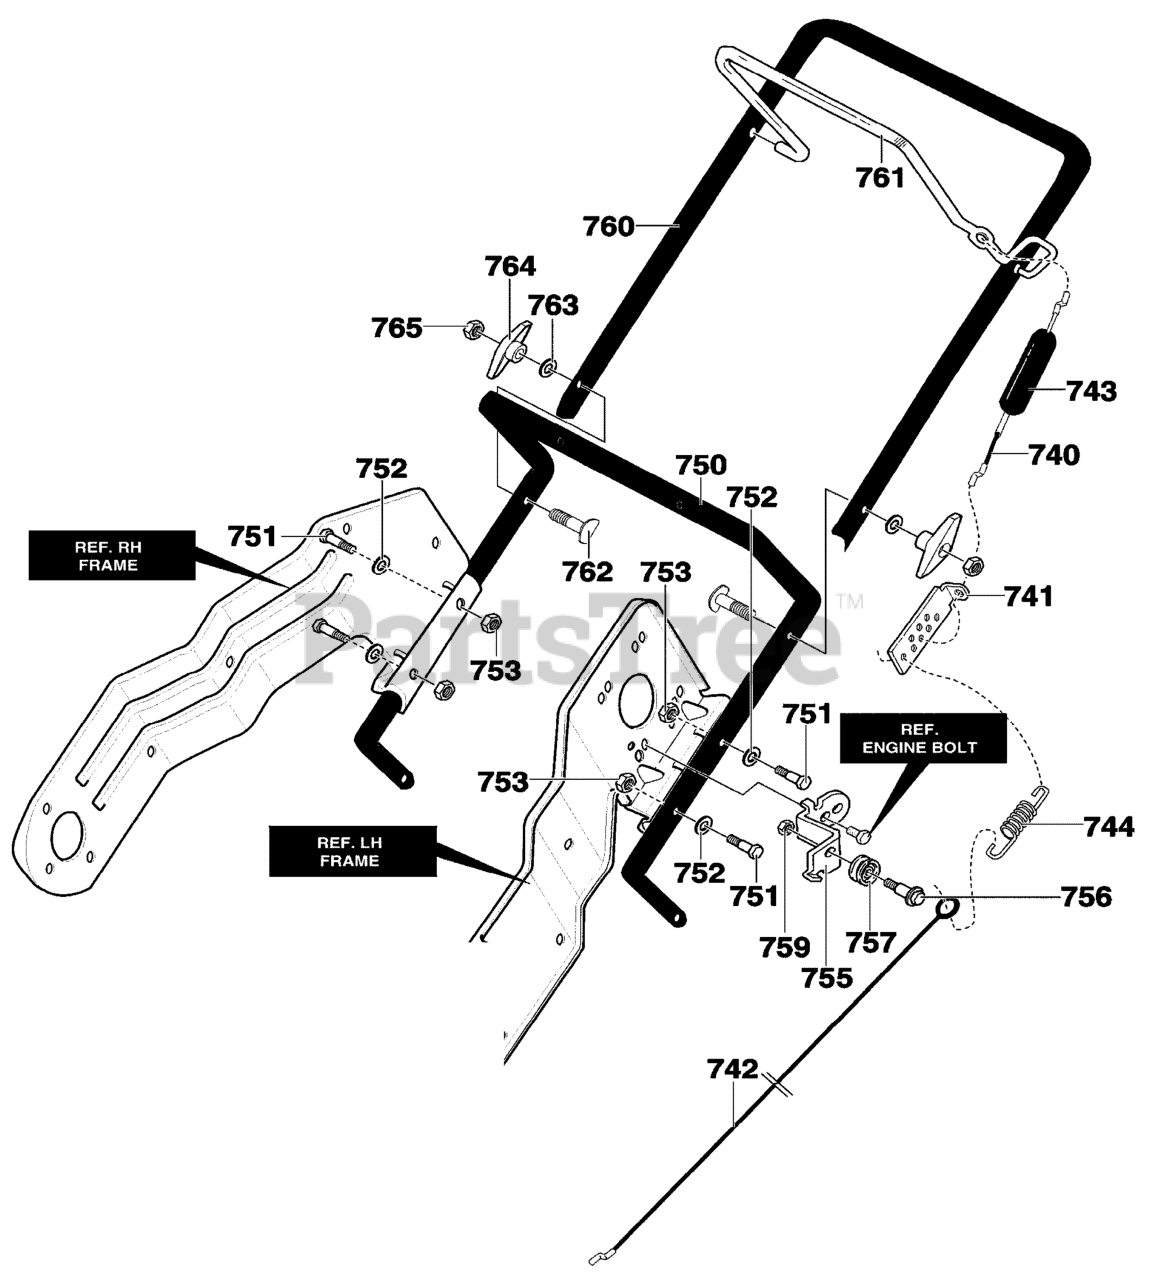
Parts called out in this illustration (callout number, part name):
740	CABLE, UPPER
741	BRACKET, CABLE ADJ
742	CABLE, LOWER CONTROL
743	BOOT, CLUTCH SPRING
744	SPRING, EXTENSION
750	HANDLE, LOWER
751	SCREW, 1/4-20X1.25
752	WASHER, FLAT
753	NUT, 1/4-20
755	BRACKET, CABLE
759	NUT, 1/4-20 YZ
760	UPPER HANDLE
761	BAIL, CONTROL
763	WASHER, FORM
764	KNOB, T 3.00 WD
765	NUT, 5/16-18
